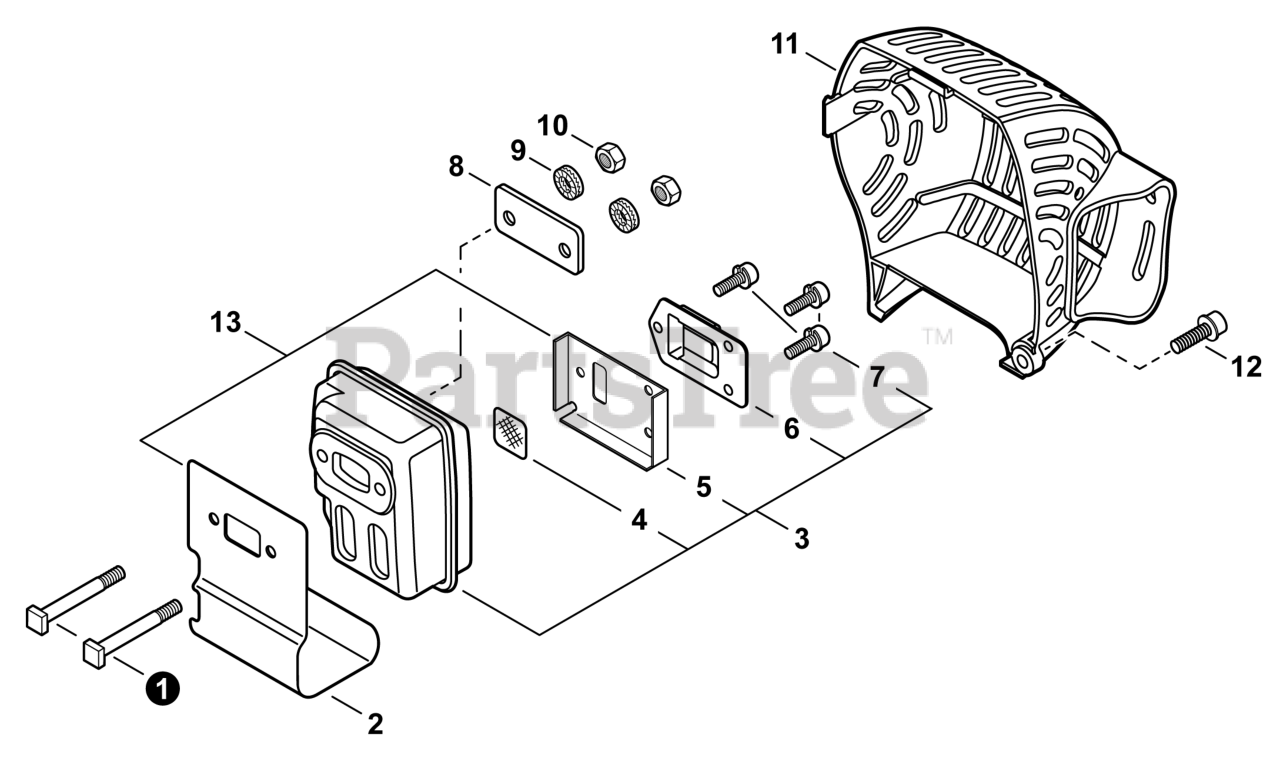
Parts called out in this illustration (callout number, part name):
1	BOLT 5x60
2	HEAT SHIELD, EXHAUST
3	MUFFLER ASSY
4	SCREEN, SPARK ARRESTER
5	GASKET, EXHAUST
6	GUIDE, EXHAUST
7	SCREW 4x10
8	PLATE, EYE
11	COVER, MUFFLER
12	BOLT 5x14
13	GASKET KIT
